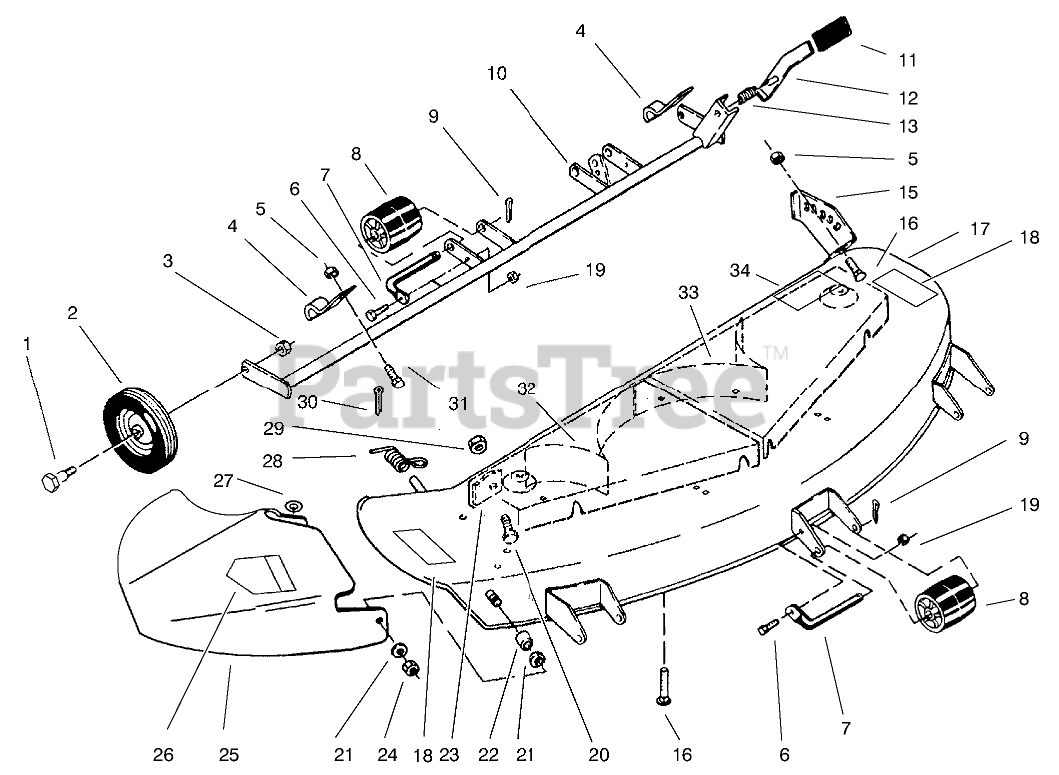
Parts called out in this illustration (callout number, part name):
1	BOLT-SHOULDER
2	WHEEL
3	NUT-HEX
4	Clamp
5	NUT-LOCK, NI
6	SCREW-HH
7	ROLLER-SHAFT
8	Roller
9	PIN-COTTER
10	Support-Gage Wheel
12	Lever
13	SPRING-COMPRESSION
15	Quadrant
16	BOLT-CARR
17	Deck-Assembly (Incl. Ref. #18, 32 & 33)
18	DECAL-DANGER
19	NUT-LOCK, NI
20	SCREW-HH
21	WASHER
22	BUSHING-PIVOT
23	GUARD-CHUTE B
24	NUT-HJ
25	Chute Assembly (Incl. Ref. #26)
26	DECAL-DANGER
27	WASHER-FLAT
28	SPRING-DEFLECTOR
29	NUT-LOCK, NI
30	PIN-COTTER
31	BOLT-CARR
32	BAFFLE-DECK RH
33	BAFFLE-DECK LH
34	DECAL - BELT & HEIGHT
